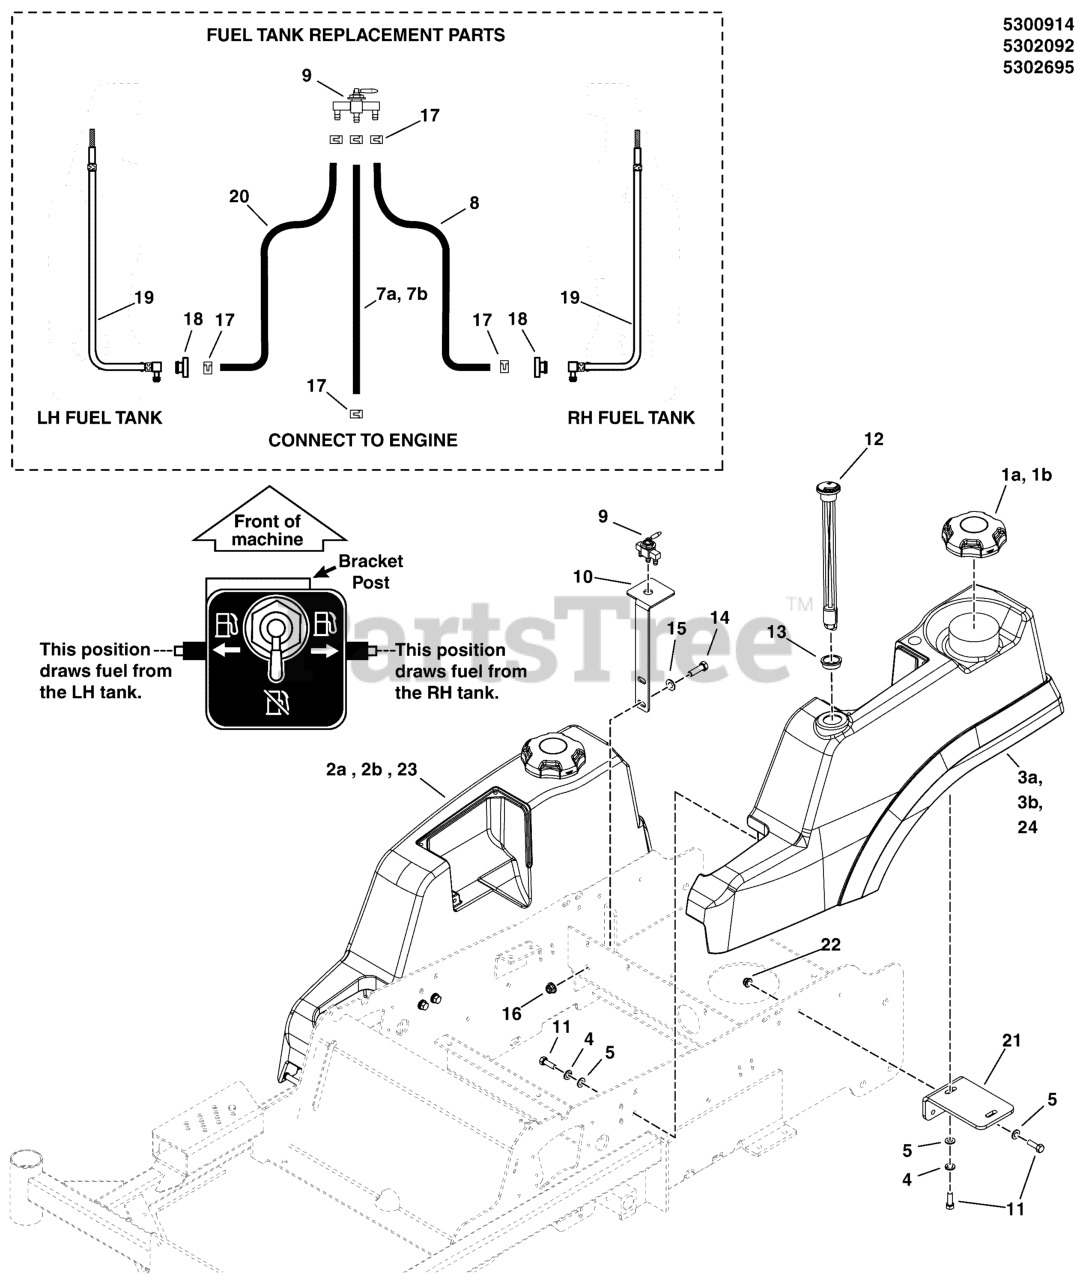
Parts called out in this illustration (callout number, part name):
4	WASHER, 5/16 LOCK CZ
5	WASHER, 5/16" SAE
8	HOSE, 24 IN
8	HOSE, 16 IN
9	VALVE, FUEL, STR. OUTLET
10	BRACKET, FUEL VALVE, IS3000 - BLK
11	BOLT, 5/16-18 X 1 GD5 YZ
12	FUEL GAUGE, 10"
13	GROMMET, FUEL GAUGE
14	BOLT, 3/8-16 X 1-1/2" GD5 CZ
15	WASHER, 3/8 SAE
16	NUT, 3/8-16 HEX NYLOCK FLANGE
17	CLAMP, HOSE, EXTERNAL, 1/2 - RED
18	BUSHING-FUEL TANK RED RUBBER
19	PICKUP TUBE ASSEMBLY, FUEL LINE
20	HOSE, FUEL, 1/4 IN, LW PRMTN, 26" LONG
21	MOUNT, TANK, REAR - BLK
22	NUT, 5/16-18 HEX NYLOCK FLANGE
23	TANK, FUEL, SNP-PRO, RH, 2013
24	TANK, FUEL, LH
